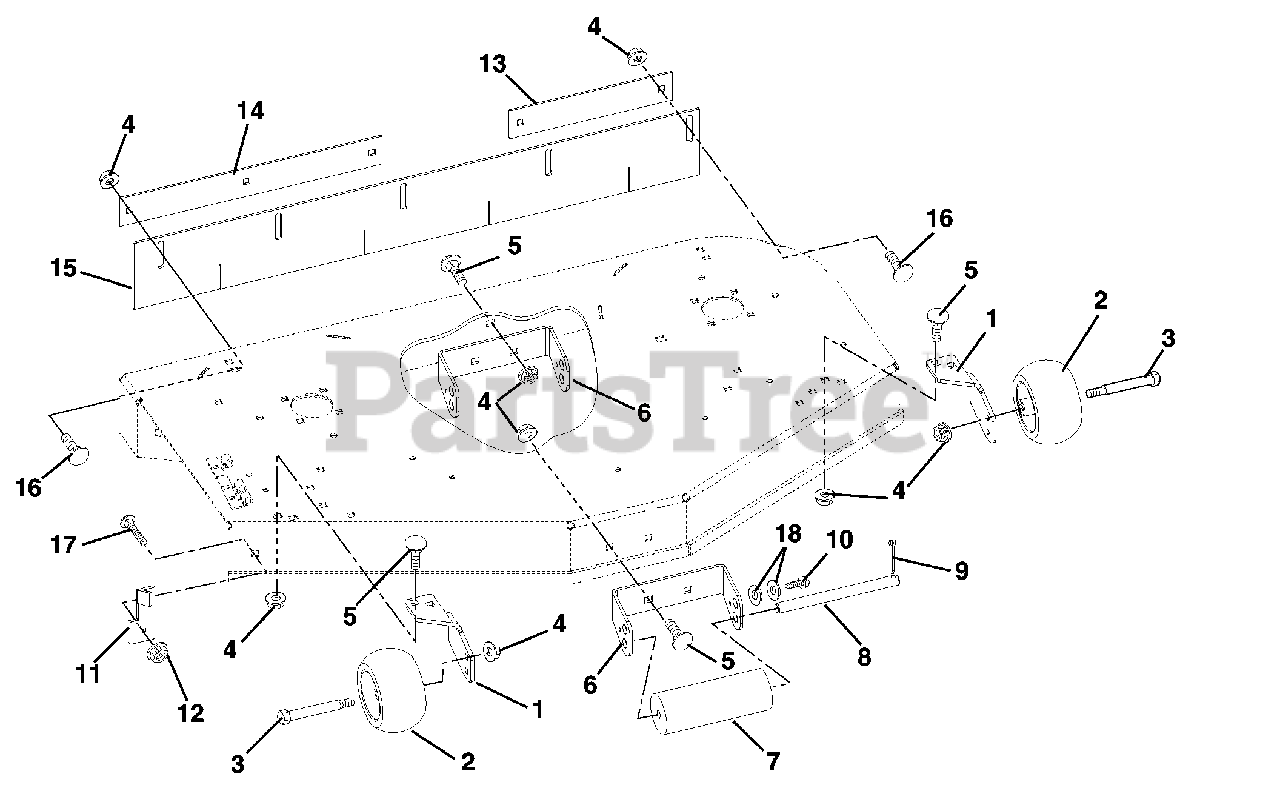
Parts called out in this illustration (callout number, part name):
1	BRACKET, ANTI SCALP
2	WHEEL 5 X 3
3	BLT-SHLDR .38-16X2.50 HWH G5
4	NUT-LK-TOP-FLG .38-16 BLKZC
5	BLT-RDHDSQNK .38-16X.75 G5BZ
6	BRACKET, ROLLER MOUNT
8	PIN, RETAINER
9	@PIN-CTR .25X1.00 YWZC
10	@SCR-TAP .25-20X.50 HWH TR YWZ
11	BRACKET, CHUTE LOCK
12	NUT-SPNLK-FLG .375-16 BKZC
13	BAR, LH RETAINER STRIPER
14	BAR, RETAINING STRIPER-40"
14	BAR, RETAINING STRIPER-44"
14	BAR, RETAINING STRIPER-52"
15	STRIPER, RUBBER-40"
15	STRIPER, RUBBER-44"
15	STRIPER, RUBBER-48"
15	STRIPER, RUBBER-52"
16	BLT-RDHDSQNK .38-16X1.00 G5BZ
17	@BLT-RDHDSQNK .38-16X1.25 BKZC
18	@WSHR-FL-STL.344X.688X.065YWZC
